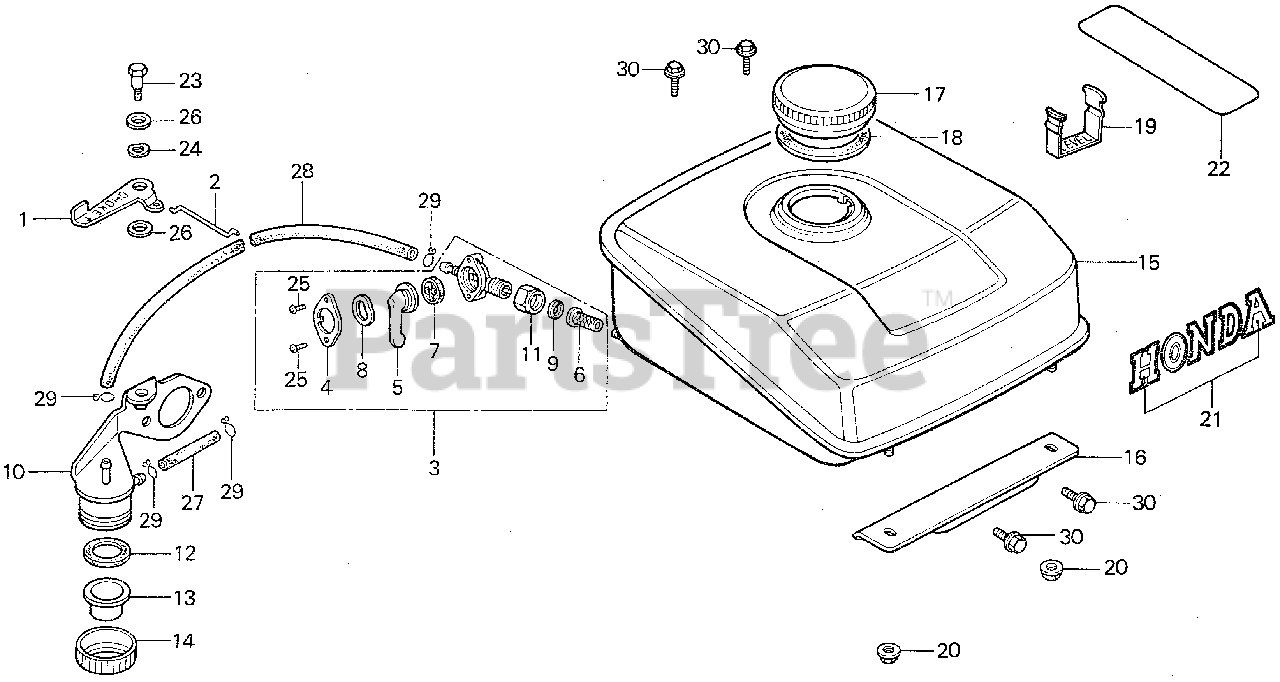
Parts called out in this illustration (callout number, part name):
1	LEVER, CHOKE
2	ROD, CHOKE (NOT AVAILABLE)
3	PETCOCK ASSY.
4	COVER, PETCOCK (NOT AVAILABLE)
5	LEVER, VALVE (NOT AVAILABLE)
6	SCREEN, STRAINER
7	GASKET, VALVE
8	SPRING, PETCOCK LEVER
9	GASKET, FUEL STRAINER CUP
10	STAY, FUEL STRAINER (NOT AVAILABLE)
11	NUT, TURN BUCKLE (NOT AVAILABLE)
12	GASKET (NOT AVAILABLE)
13	CUP, STRAINER (NOT AVAILABLE)
14	NUT, RING (NOT AVAILABLE)
15	TANK, FUEL *NH31* (MCKINLEY WHITE) (NOT AVAILABLE)
16	STAY, FUEL TANK *R8* (BRIGHT RED)
17	CAP, FUEL FILLER
18	GASKET, FUEL FILLER CAP
19	PLATE, FUEL LEVEL
20	NUT, FLANGE (6MM)
21	MARK, TOP COVER
22	MARK A, CAUTION
23	BOLT, CHOKE LEVER
24	WASHER, WAVE (NOT AVAILABLE)
25	SCREW, PAN (3X6)
26	WASHER, PLAIN (8MM)
27	BULK HOSE, FUEL (4.5X3000) (4.5X30)
28	BULK HOSE, FUEL (4.5X3000) (4.5X80)
29	CLIP, TUBE (B8)
30	BOLT, FLANGE (6X12)
